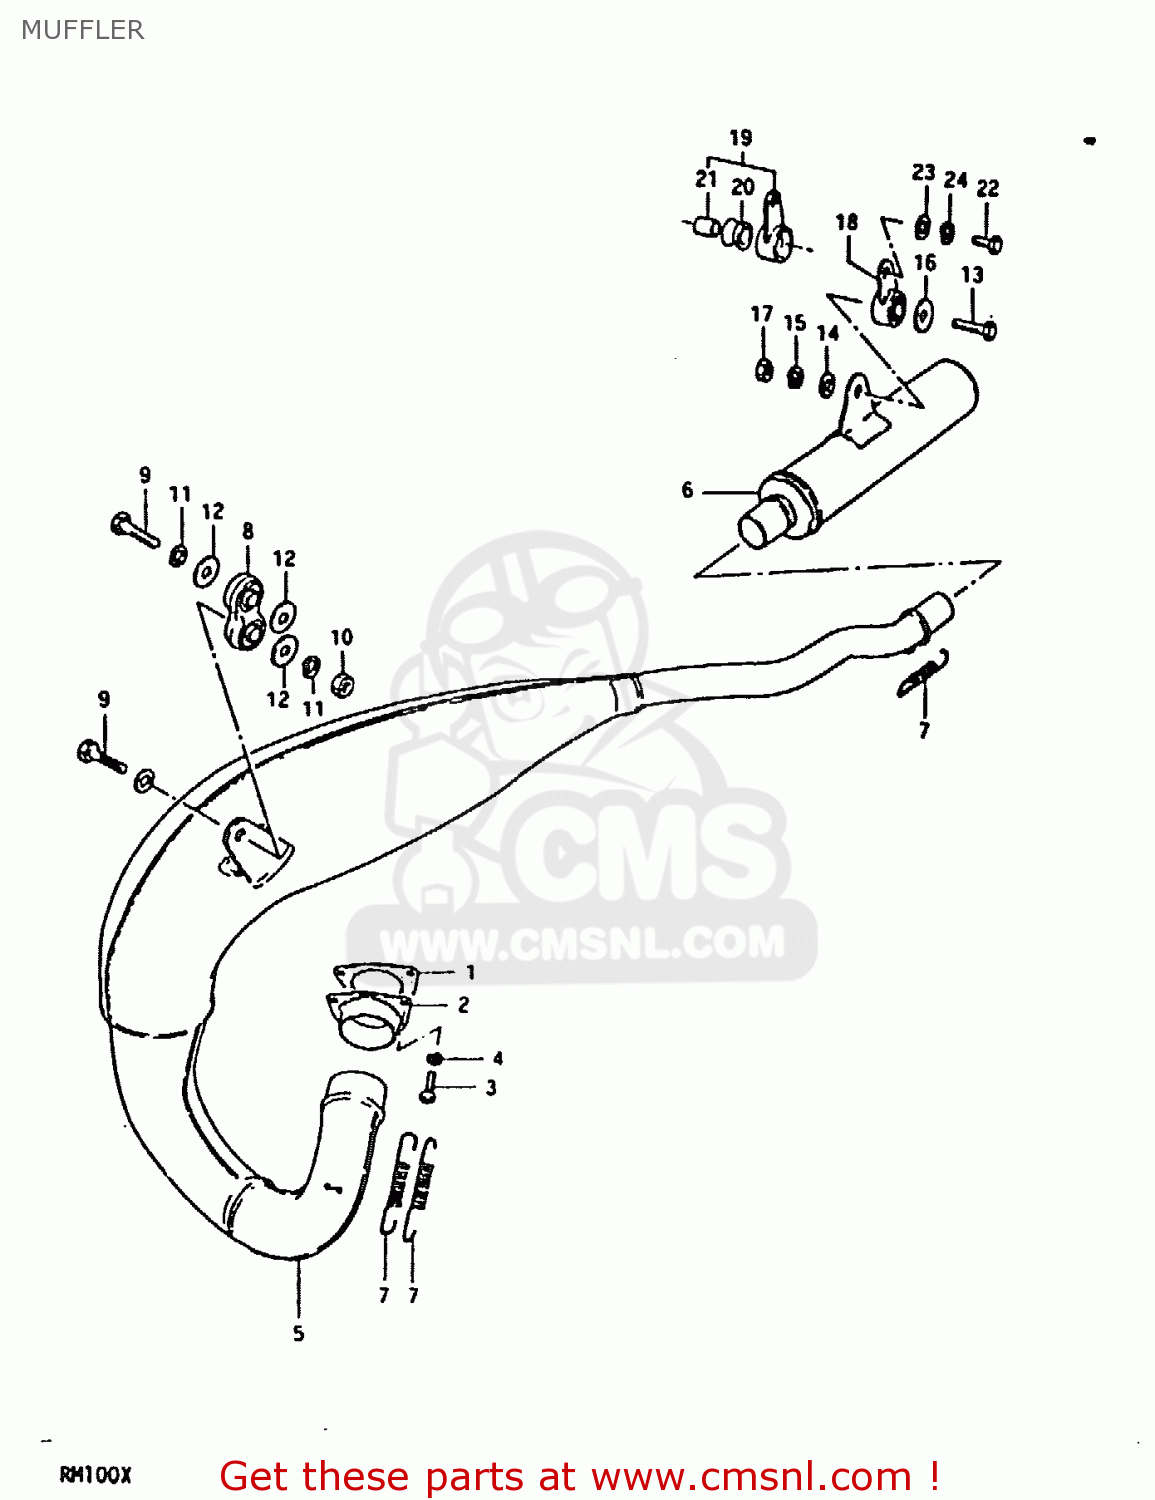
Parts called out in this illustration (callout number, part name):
1	GASKET,EXHAUST PIPE (MCA)
2	FLANGE,EXHAUST PIPE
3	SCREW
4	LOCK WASHER
5	BODY,MUFFLER
6	BODY,MUFFLER
7	SPRING
8	DAMPER,MUFFLER
9	BOLT
10	NUT
11	LOCK WASHER
12	WASHER
13	BOLT (8X30)
14	WASHER
15	LOCK WASHER
16	WASHER (8.5X29X1.6)
17	NUT
18	DAMPER,MUFFLER SUPPORT
19	DAMPER,MUFFLER SUPPORT 2ND
20	CUSHION
21	SPACER (8.2X12X17)
22	BOLT
23	WASHER
24	LOCK WASHER
